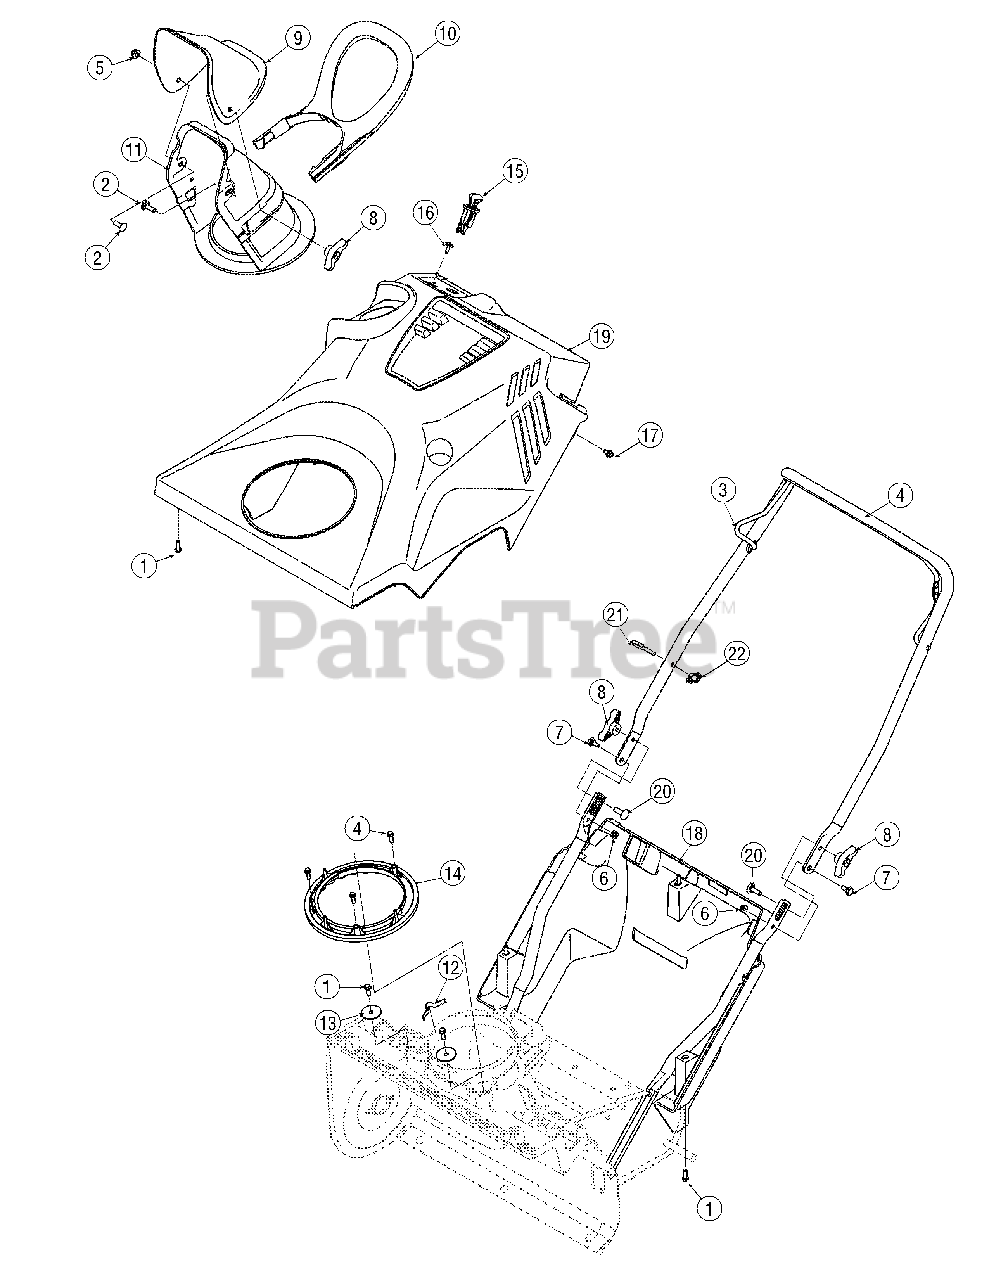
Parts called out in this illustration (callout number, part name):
1	Screw, 1/4-15 x 0.75
2	Carriage Bolt, 5/16-18 x .750
3	Auger Bail
4	Upper Handle
5	Flange Lock Nut, 5/16-18
6	Flange Lock Nut, 1/4-20
7	Shoulder Screw, 1/4-20 x .375 x .148
8	Wing Knob, 5/16-18
9	Upper Chute
10	Chute Handle
11	Lower Chute
12	Chute Adjustment Spring
13	Flat Washer, .28 x 1.51 x .066
14	Chute Ring
15	Ignition Switch Assembly
16	Hex Washer Screw, 1/4-15 x .50
17	Hex Washer Screw, 1/4-20 x .500
18	Bottom Cover
19	Top Cover
20	Carriage Screw, 5/16-18 x 1.00
21	Eye Bolt, 1/4-20
22	Handle Knob
